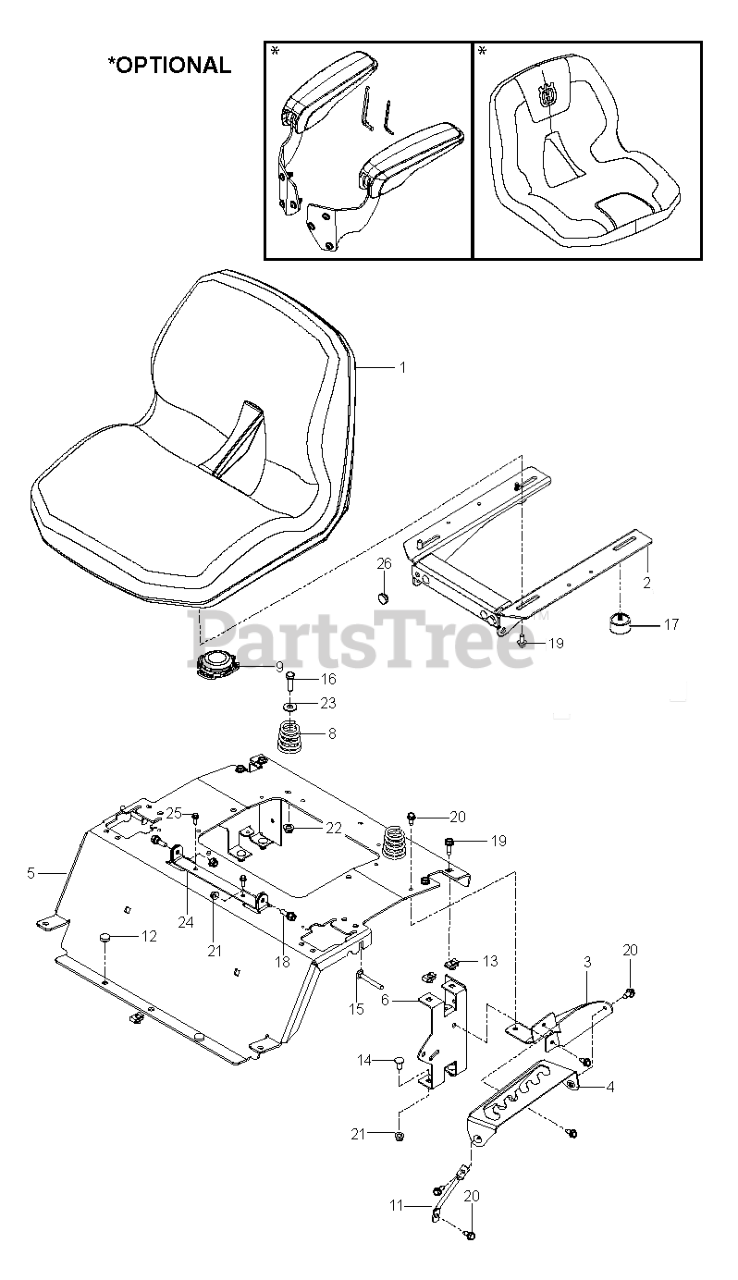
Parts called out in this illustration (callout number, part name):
3	PLATE.SUPPORT.DECK.LIFT.X431
4	PLATE.DECK.LIFT.X431
5	PLATE.SUPPORT.SEAT.RZ.ORANGE
6	SUPPORT REAR SEAT BLACK
8	SPRING.COMPRESS.SEAT.TAPERED
9	SWITCH.SEAT.DP W/RAMPS
11	SUPPORT.LEG.DECK.LIFT
12	GROMMET.BUMPER
13	U-CLIP 5/16-18 NUT RETAINER
14	BOLT 5/16C X 3/4" CARRIAGE
15	RHSNB 5/16-18 X 2-1/2 GR5 ZD
16	BOLT
17	BUMPER 5/16-18 CLEAR ZINC
18	BOLT, SHOULDER
19	HHFS 5/16-18 X 3/4
20	BOLT.5/16HEX.WHS.HD
21	5/16-18 NYLOC FLANGE NUT
22	NUT T
23	RP WASHER 3/8 FLAT
24	BRACKET.SEAT.REINF.X668
25	SCREW.FLG.LOCKING.1/4-20X.75
26	GROMMET, BUMPER
